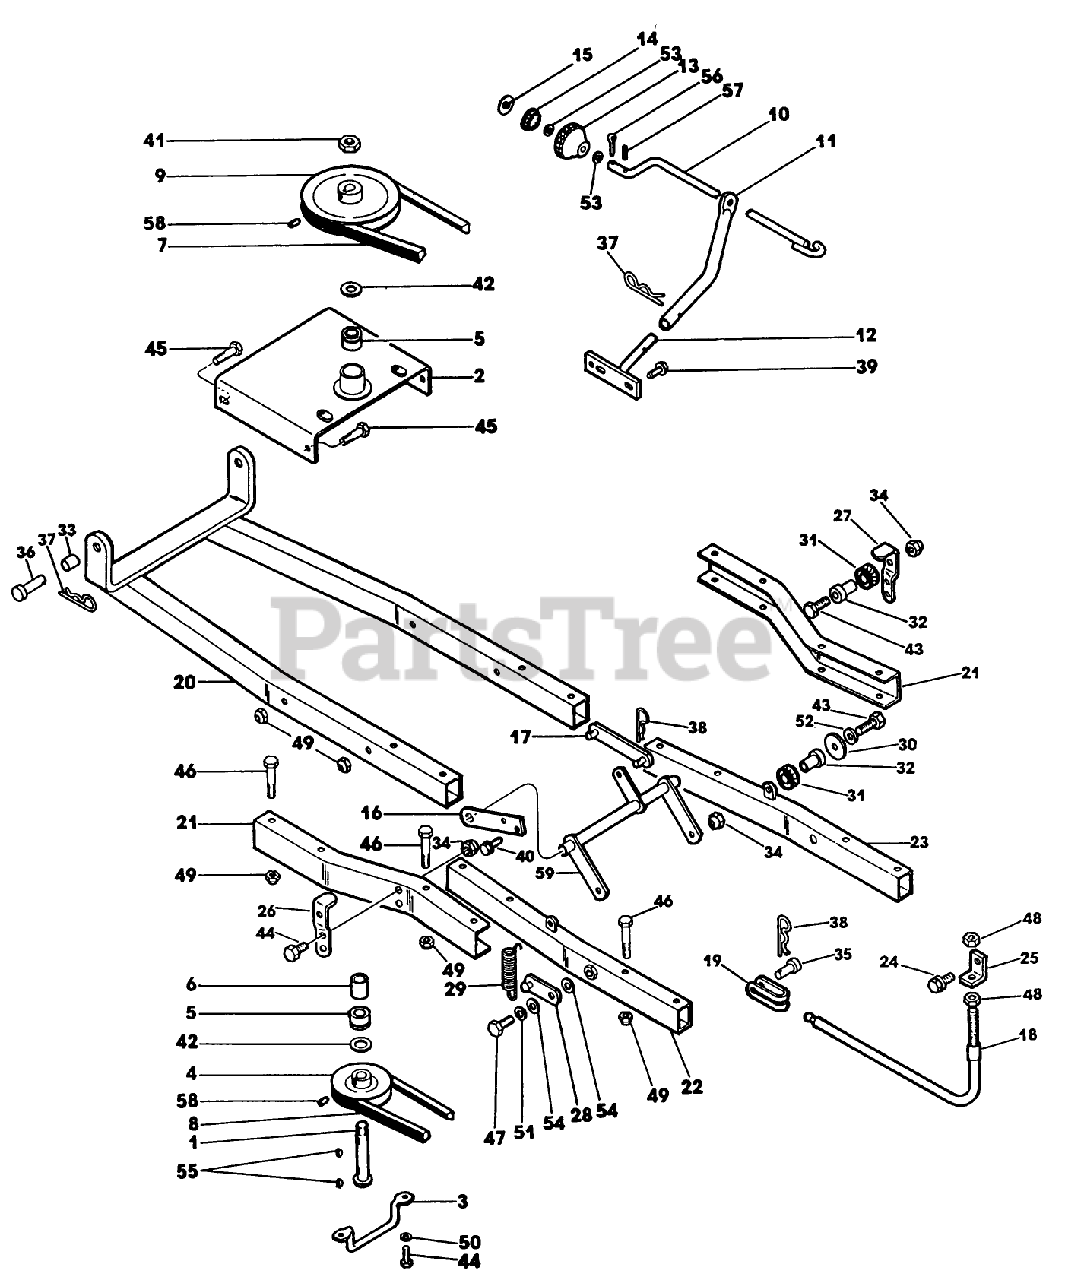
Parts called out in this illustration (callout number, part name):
1	SHAFT AY *NP
2	SUPPORT ASSY PULLY
8	V-BELT SECONDARY
11	TUBE-CRANK
13	KNOB
17	LIFT LINK
18	CABLE LIFT
22	FRONT FRAME AY RH
34	NUT
38	PIN - SPRING CLIP
42	WASHER-SHIM
44	SCREW - HEX
48	NUT SS
49	NUT-LOCKING
53	WASHER
58	SET SCREW
